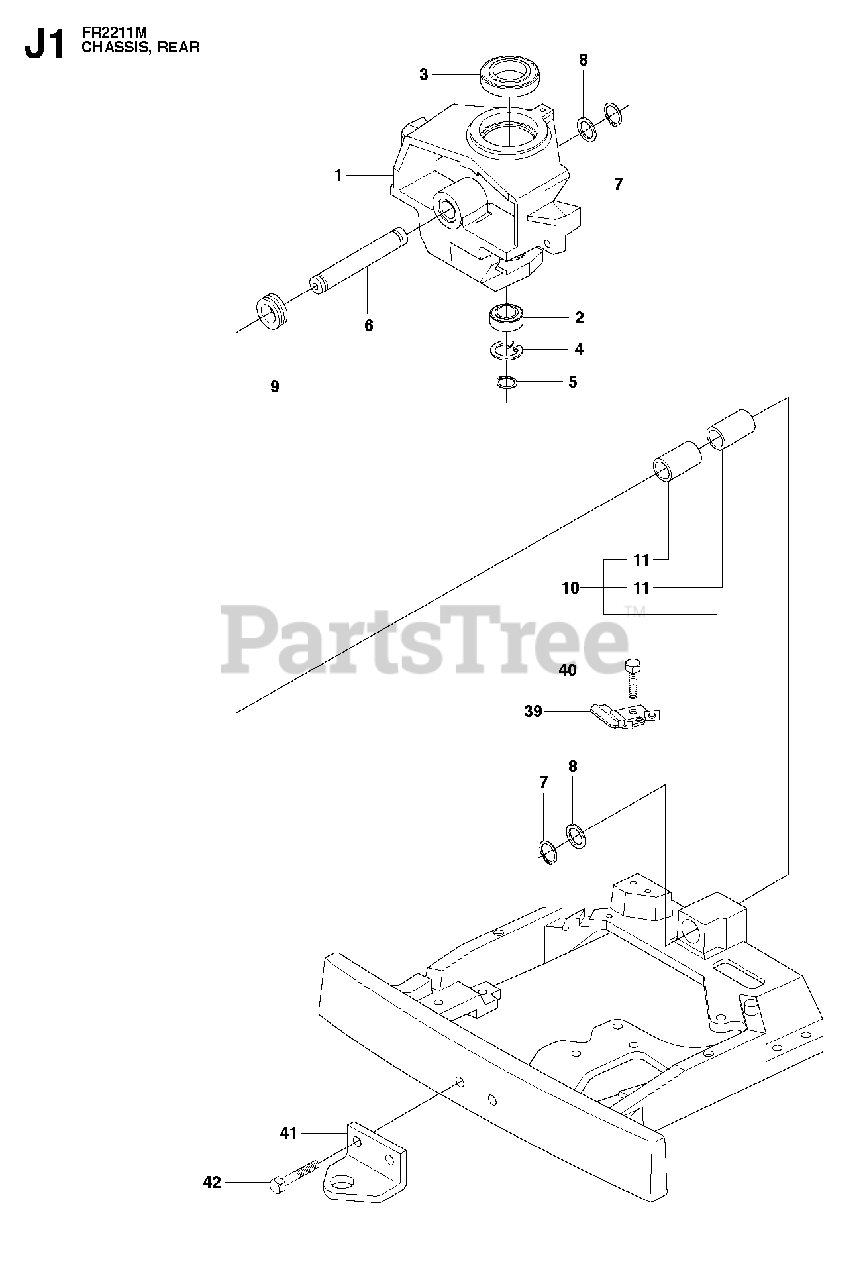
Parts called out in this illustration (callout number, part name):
2	BALL BEARING 6005-2RS
3	BALL BEARING 6010 2RS1
4	CIRCLIP SGH 47
5	RETAINING RING SGA 25
7	RETAINING RING SGA 25
11	BUSHING
41	DRAW RING
42	SCREW M10X25
